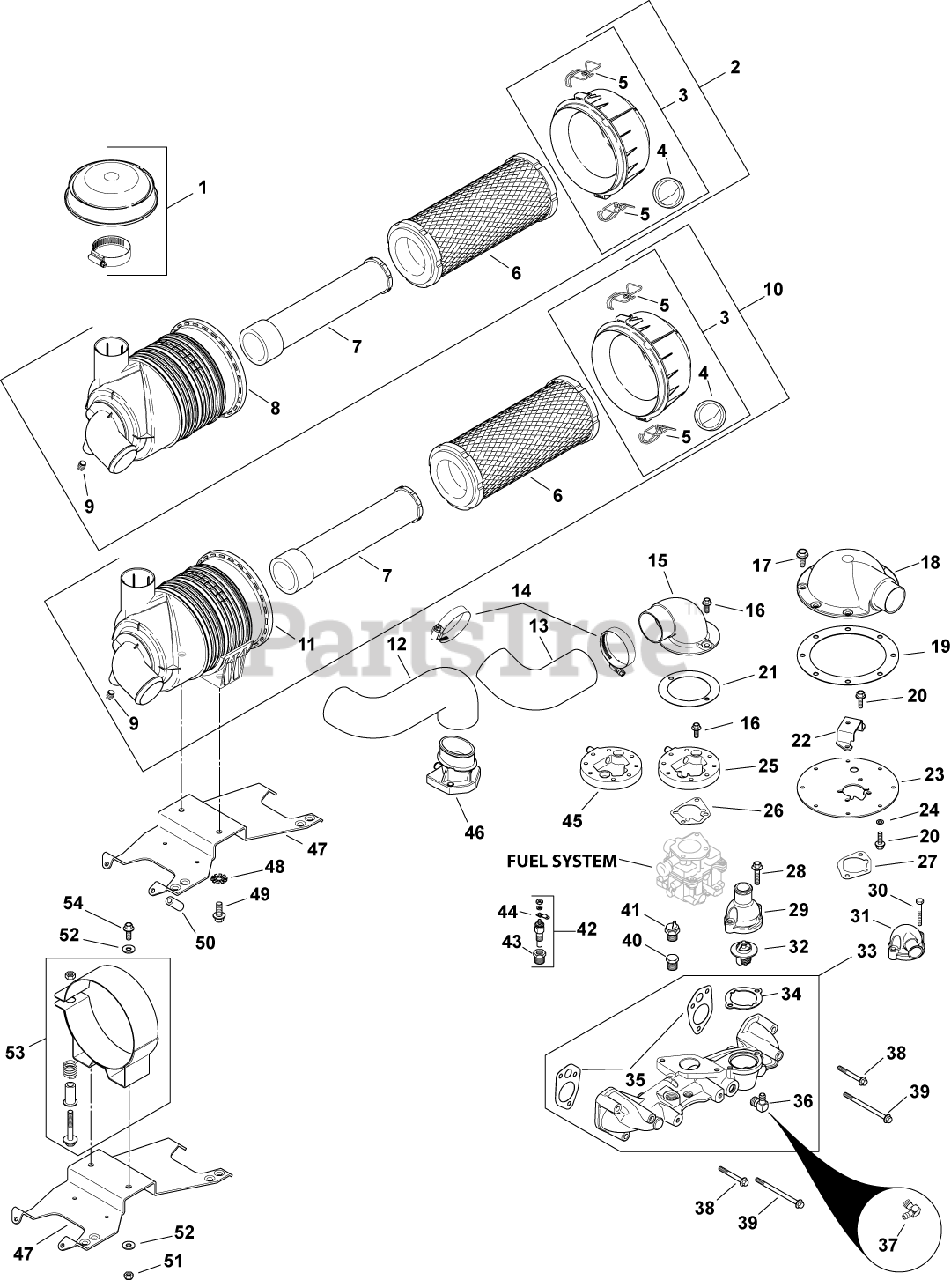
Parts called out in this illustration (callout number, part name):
1	HOOD, AIR CLEANER (5.25)-USE 25 324 04-S
3	COVER ASSEMBLY, AIR CLEANER
4	VALVE, DUST EJECTOR
5	CLIP - USE 62 154 07-S
6	ELEMENT, AIR FILTER - PRIMARY
7	ELEMENT, AIR FILTER - SAFETY
9	PLUG, PIPE
10	AIR CLEANER, CANISTER
11	HOUSING, HEAVY DUTY A/C
13	HOSE, AIR CLEANER
14	CLAMP, HOSE
15	ADAPTER, REMOTE AIR CLEANER
16	SCREW, FLG M6X1.0X16
21	GASKET, ADAPTER
25	ADAPTER ASSY (CH18 / 20)-USE 24 029 97-S
26	GASKET, AIR CLEANER BASE
28	SCREW - USE 25 086 124-S
29	HOUSING, THERMOSTAT
32	KIT, THERMOSTAT - USE 66 453 02-S
33	MANIFOLD, INTAKE - USE 66 164 32-S
34	GASKET, THERMOSTAT
35	GASKET, INTAKE MANIFOLD
36	CONNECTOR, HOSE
37	CONNECTOR
38	SCREW, FLG M6X1.0X50
39	SCREW, FLG M6X1.0X90
40	PLUG, HD PIPE 3/8"
47	BRACKET, A/C BASE - USE 66 126 74-S
48	WASHER,INT EXT TOOTH LOCK 5/16"
49	SCREW, FLG M8X1.25X20
51	NUT, LOCK M6X1.0
52	WASHER, FLAT 1/4" (O.D. 5/8")
53	BRACKET, AIR CLEANER
54	SCREW, FLG M6X1.0X16
